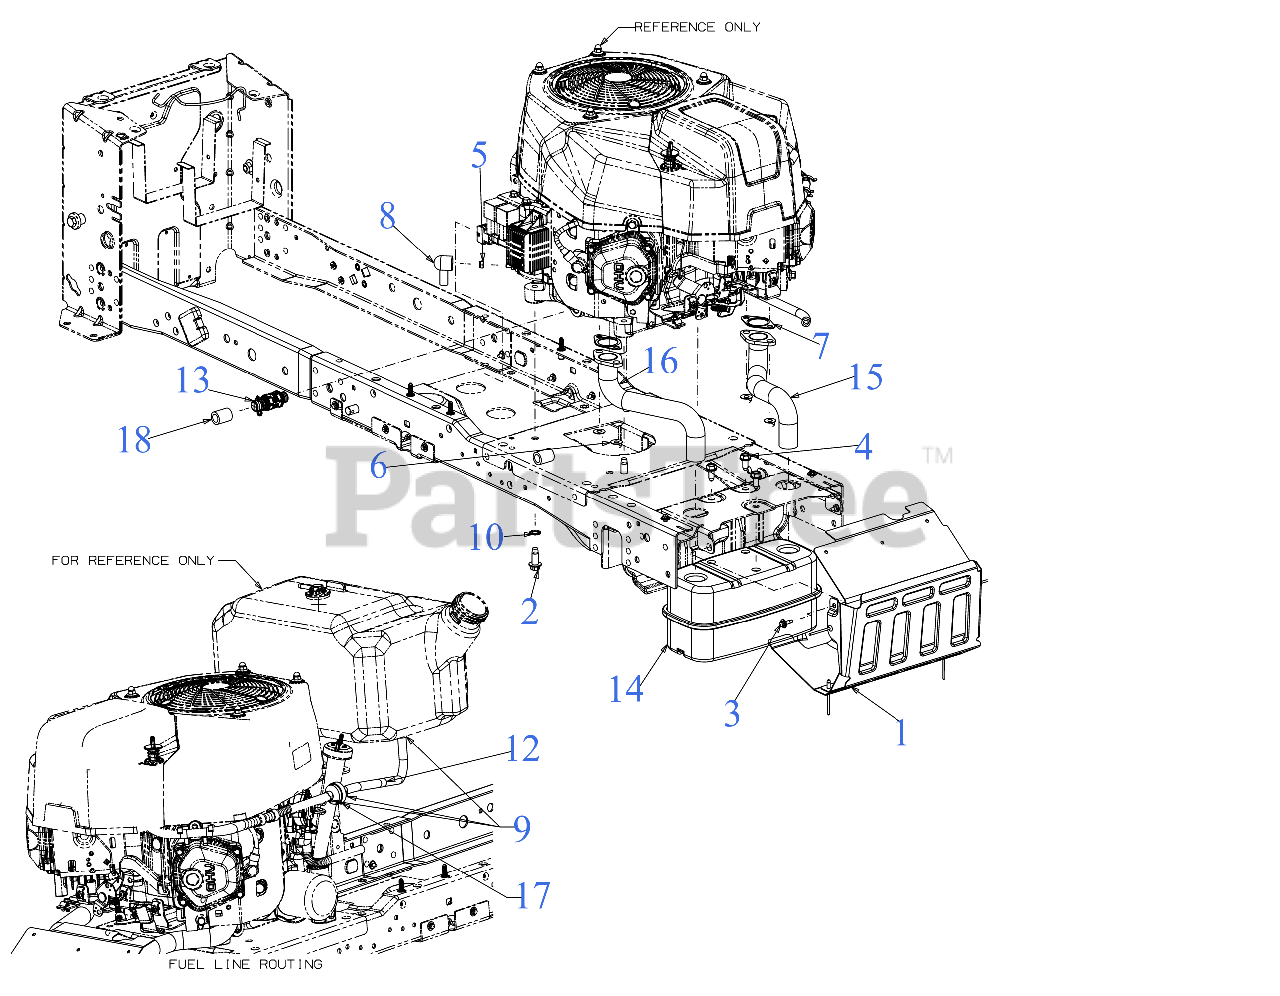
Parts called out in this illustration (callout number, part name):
1	MUFFLER SHIELD ASSEMBLY
2	SCREW 3/8-16 x 1
3	SCREW M6-1 x .625
4	SCREW M8-1.25 x .750
5	HEX NUT IK:M6
6	HEX FLANGE NUT M8X
7	EXHAUST GASKET
8	TERMINAL COVER RED
9	HOSE CLAMP 1/20
10	LOCK WASHER 3/8
12	FUEL HOSE LOW PERMEATION 13"
13	OIL DRAIN VALVE
14	EXHAUST MUFFLER TWIN
15	EXHAUST PIPE (LH)
16	EXHAUST PIPE (RH)
17	FUEL FILTER
17	Genuine Factory Parts FUEL FILTER
18	DRAIN HOSE 14''
